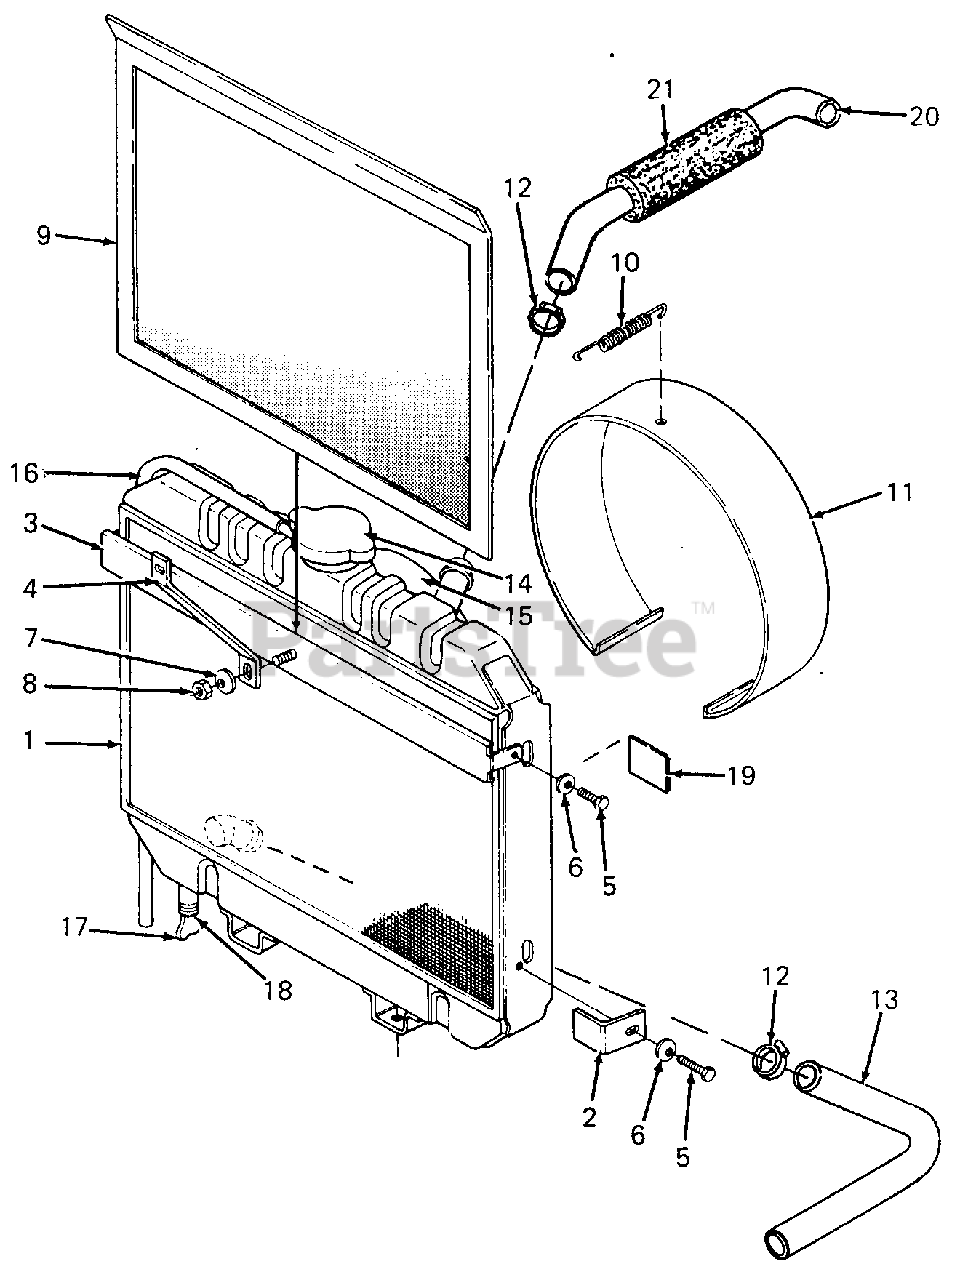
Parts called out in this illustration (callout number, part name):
1	Radiator Assy
2	Bracket, Screen Support
3	Brace, Radiator
5	Screw, Hex Cap, M6 X 14 mm Lg GR5
6	Washer, Bell, .265 X .75 X .062 Thk
7	Washer, Bell, .345 X .88 X .06 Thk
8	Nut, Hex Center Lock, 5/16-18
9	Screen, Radiator
10	Spring, Extension, .38 OD X 3.25 Lg
11	Extension, Radiator
12	Clamp, Hose
13	Hose, Lower Water
14	Cap, Radiator
16	Tube, Overflow
19	Label, Radiator
20	Hose, Upper Water
21	Cover, Foam Hose
